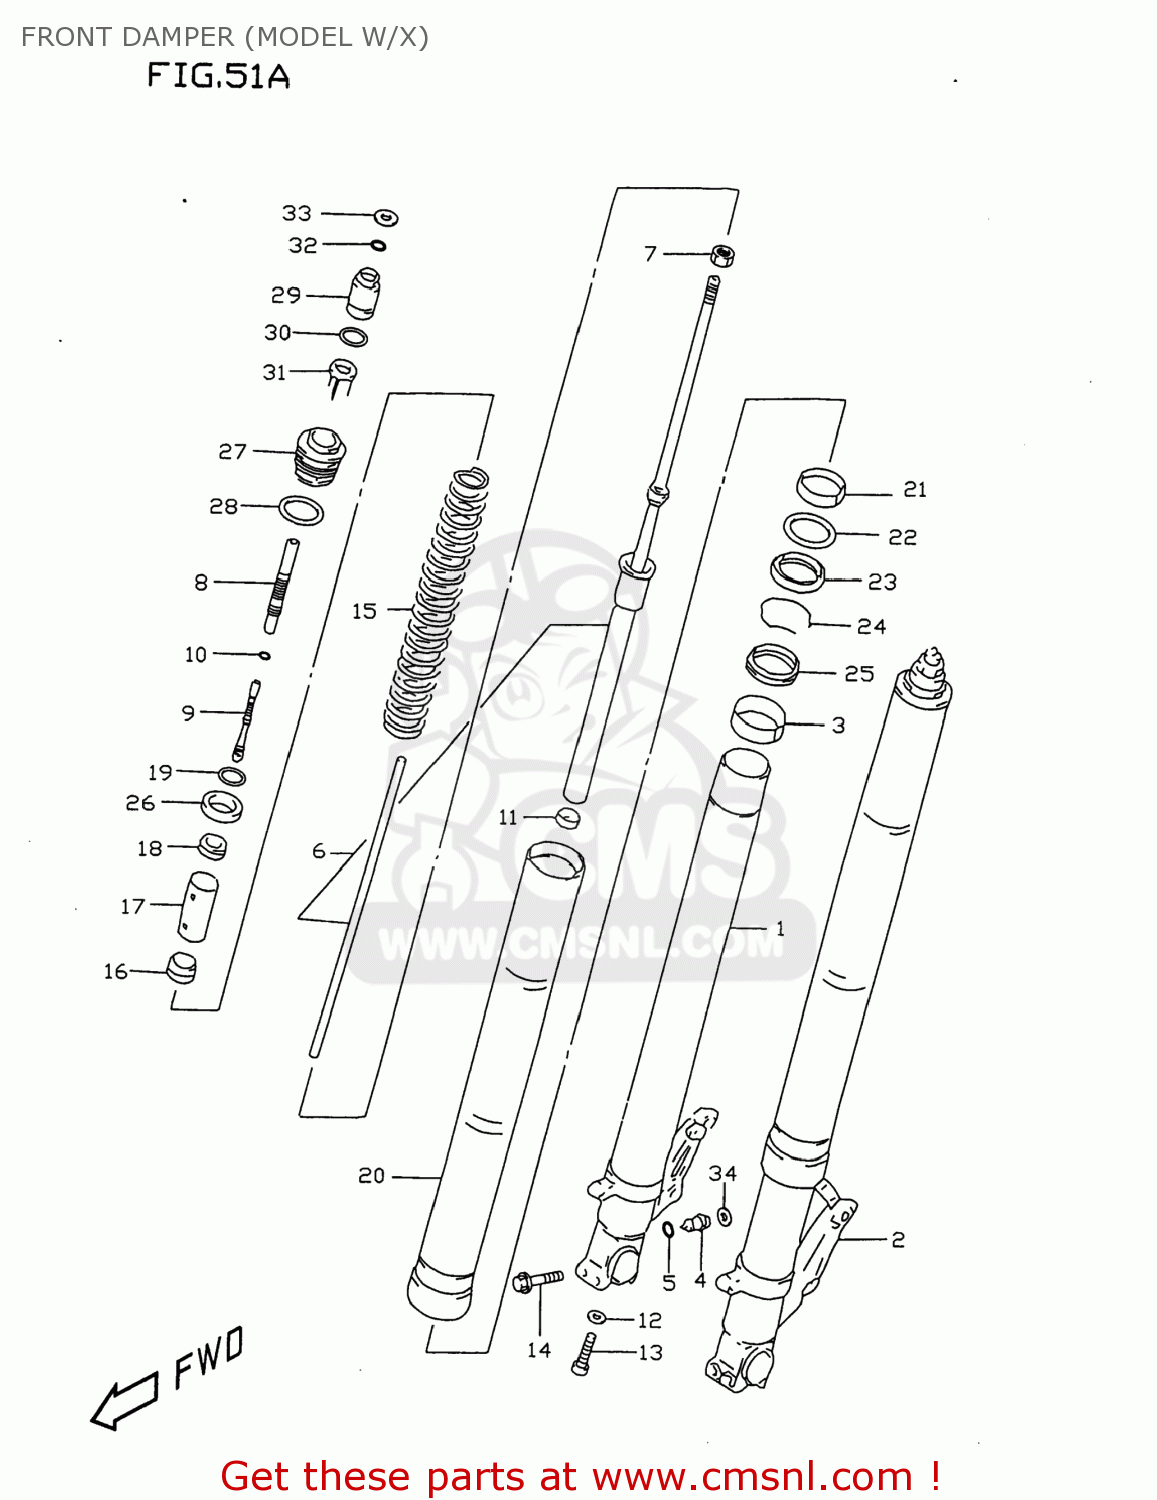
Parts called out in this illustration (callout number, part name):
1	TUBE,INNER,R
2	TUBE,INNER,L
3	BUSH,SLIDE
4	PIECE,ADJUST
5	O RING(D:2.5,ID:13.8)
6	ROD,FR DAMPER
7	NUT
8	CASE,ADJUSTER
9	PIECE,ADJUST
10	O RING(D:1.9,ID:3.8)
11	PLATE,CENTERING
12	WASHER(10X15X1.5)
13	BOLT
14	BOLT
15	SPRING,FR
16	JOINT,SPRING
17	COLLAR,SPRING
18	GUIDE,SPRING UPR
19	GUIDE,SPRING
20	TUBE,OUTER
21	BUSH,GUIDE
22	SPACER,SEAL
23	SEAL,OIL
24	CIRCLIP,FORK OIL SEAL
25	SEAL,DUST
26	RUBBER,SEAT
27	BOLT,FORK
28	O RING,FORK BOLT
29	ADJUSTER,SPRING
30	O RING
31	PLATE,SPRING ADJUSTER
32	RING,STOPPER
33	LABEL,ADJUST PIECE UPR
34	LABEL,ADJUST PIECE LWR
